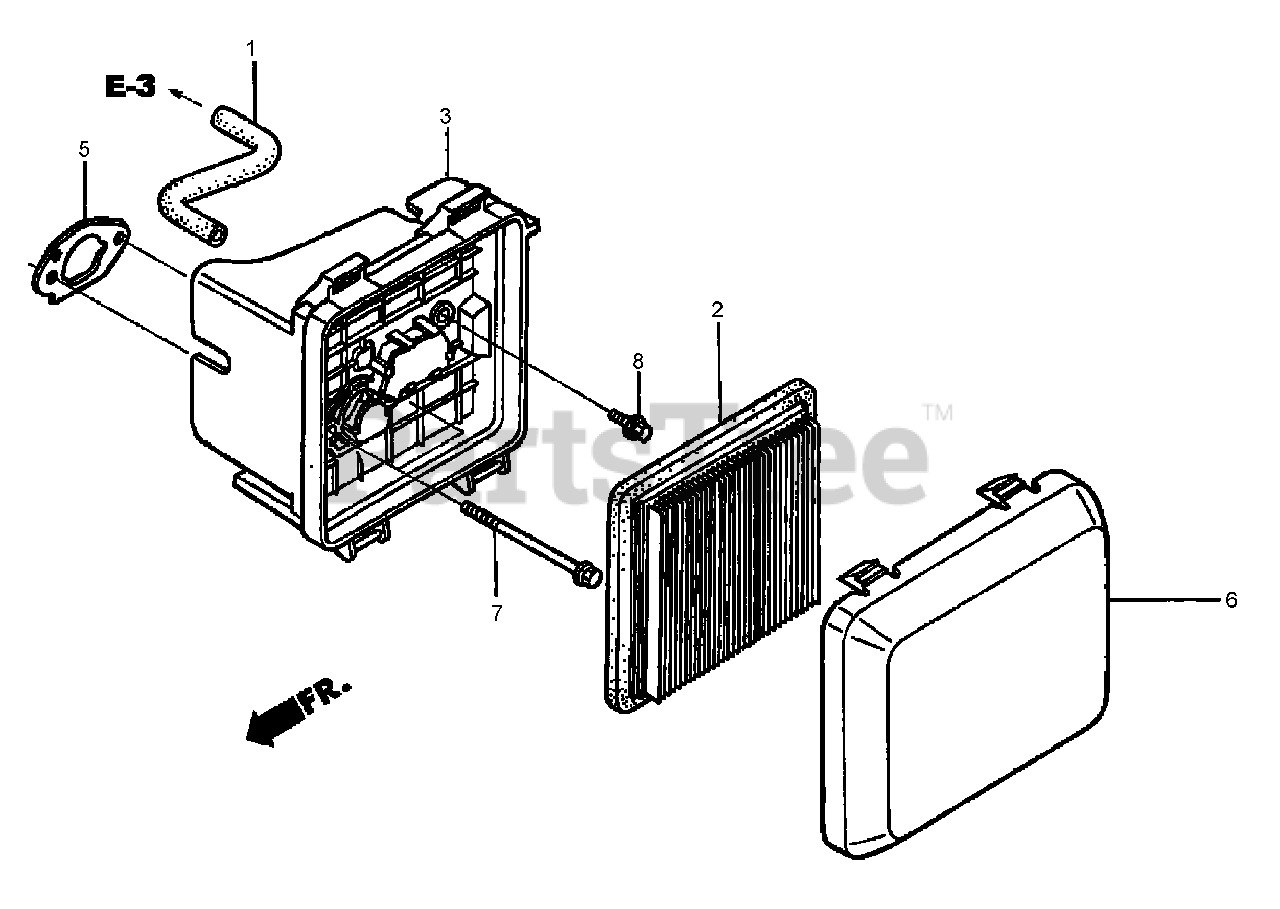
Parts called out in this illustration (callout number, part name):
1	TUBE-BREATHER
2	ELEMENT-CLEANER, AIR
3	AIR CLEANER CASE ASM
5	GASKET-CLEANER, AIR
6	COVER-CLEANER, AIR
7	BOLT-FLANGE (6X86) (CT200)
8	BOLT-FLANGE (6X14)
